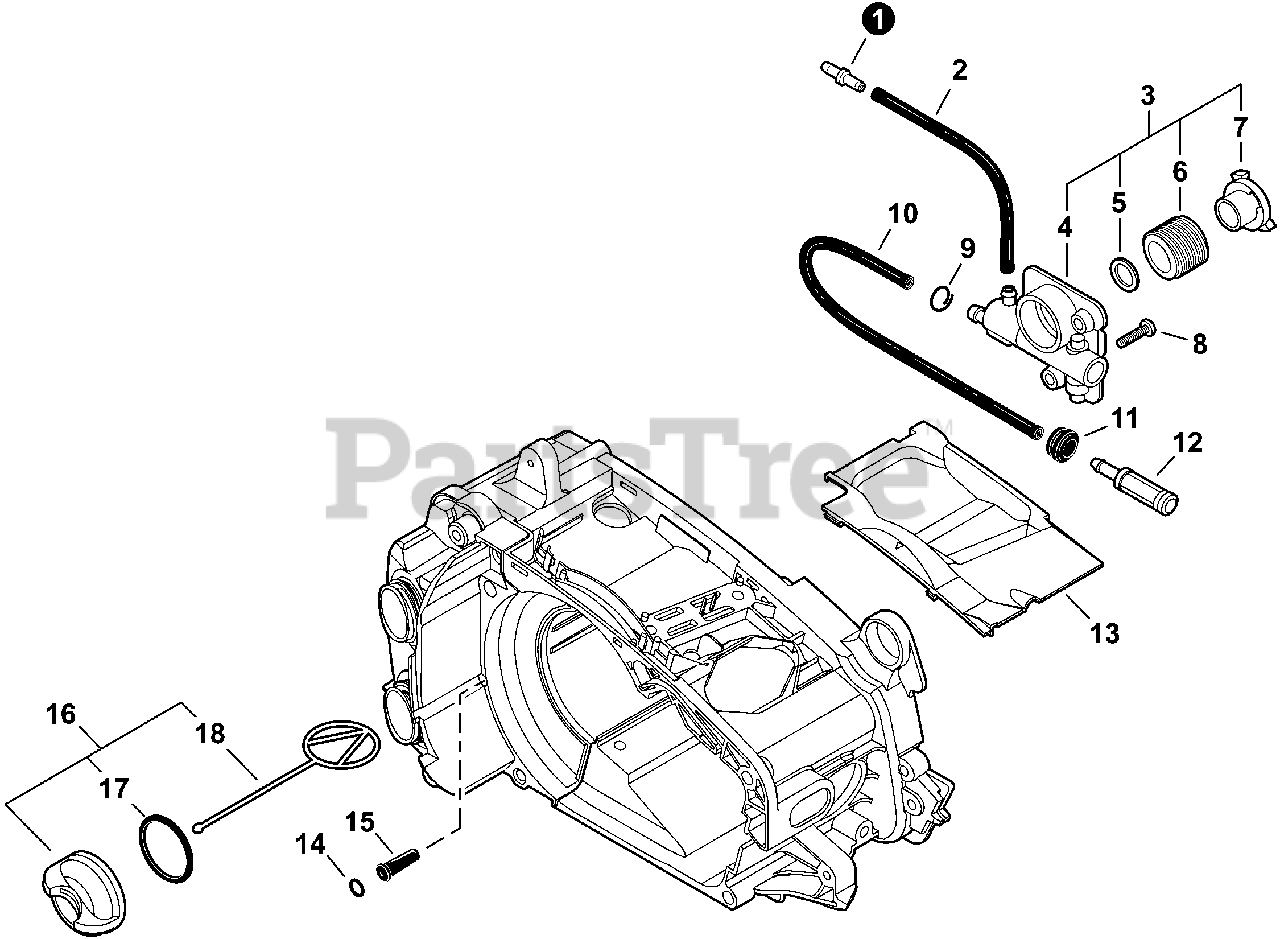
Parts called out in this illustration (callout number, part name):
1	CONNECTOR, PIPE
2	PIPE, 3×6×45 BLACK
3	AUTO-OILER ASSY
4	AUTO-OILER
5	WASHER 10.5×17.4×1.8
6	GEAR, WORM
7	COLLAR 10
8	BOLT, TORX 4×12
9	CLIP Ø6.5MM
10	PIPE, OIL 3×6×160
11	GROMMET
12	FILTER, OIL
13	COVER, DUST
14	O-RING S-4
15	VENT ASSY
16	CAP ASSY, BLACK
17	O-RING 18
18	CONNECTOR, CAP L= 60mm
